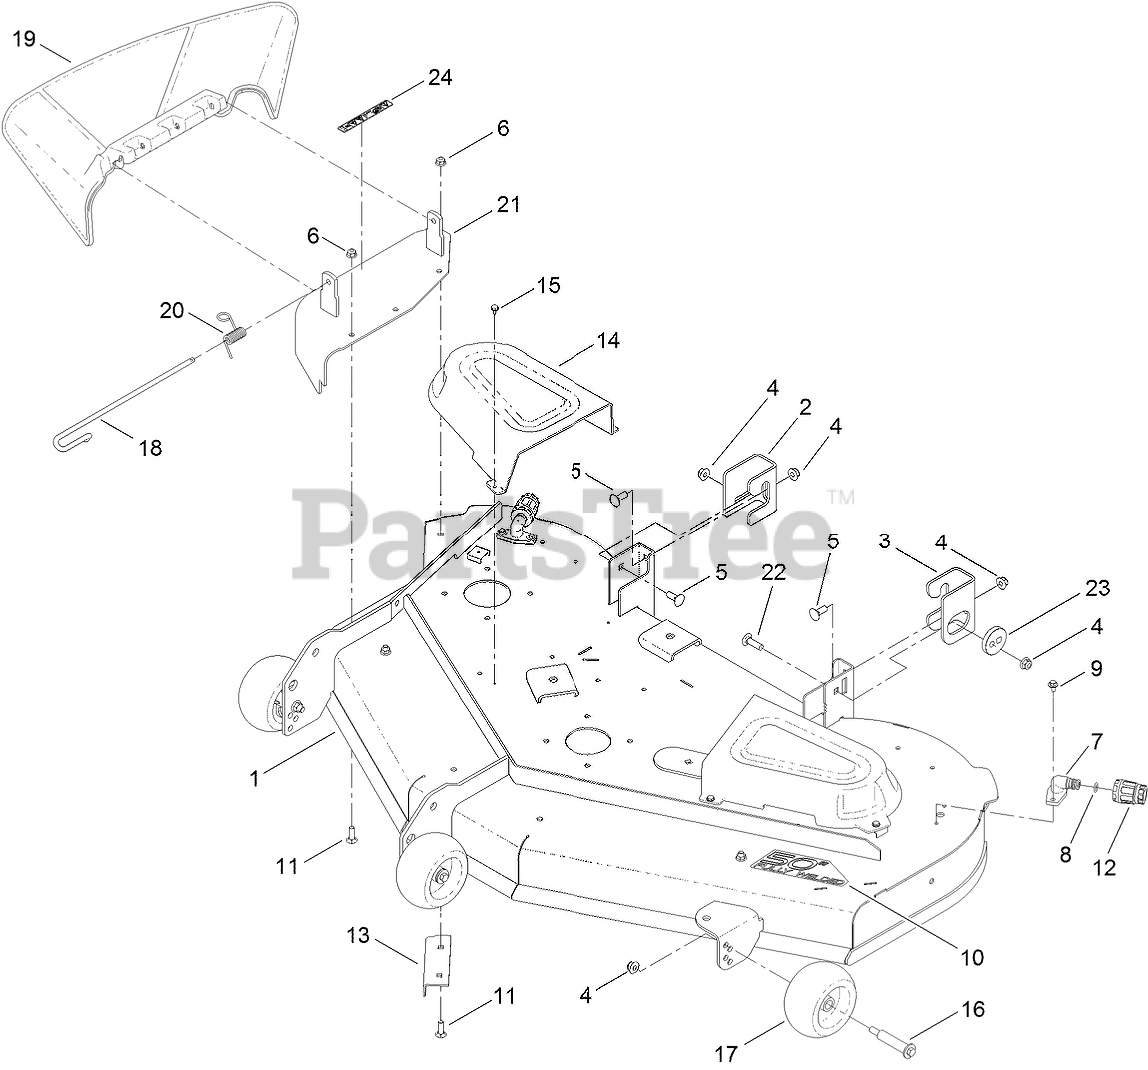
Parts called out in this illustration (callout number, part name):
1	50 INCH DECK AND DECAL ASM
2	BRACKET-HANGER, RH
3	BRACKET-HANGER, LH
4	NUT-HF, NI
5	BOLT-CARR
6	NUT-HF, NI
7	FITTING-WASHOUT
8	O-RING
9	SCREW-HHFTF
10	DECAL-DECK
11	SCREW-CARR
12	CONNECTOR-HOSE
13	BAFFLE-CUTOFF
14	COVER-BELT
15	SCREW-HWHTF
16	BOLT-SHOULDER
17	ROLLER-SCALP, ANTI
18	PIN-CHUTE
19	DEFLECTOR-DISCHARGE
20	SPRING-TORSION
21	COVER-DISCHARGE
22	SCREW-CARR
23	ECCENTRIC
24	DECAL-DANGER
